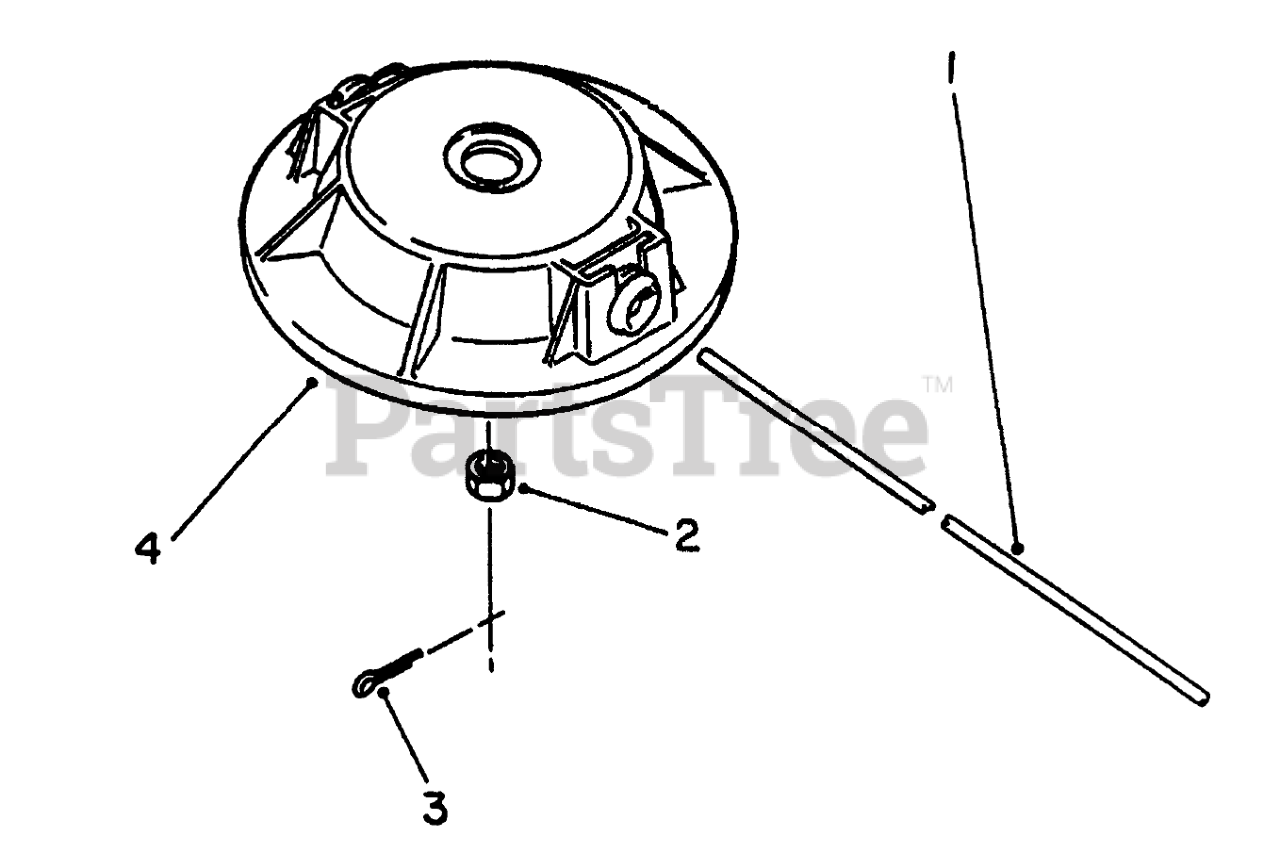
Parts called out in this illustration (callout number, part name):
1	Line-Cutting
3	1/16 X 1 LG COTTER PIN
4	CUTTER HEAD-PLASTIC
